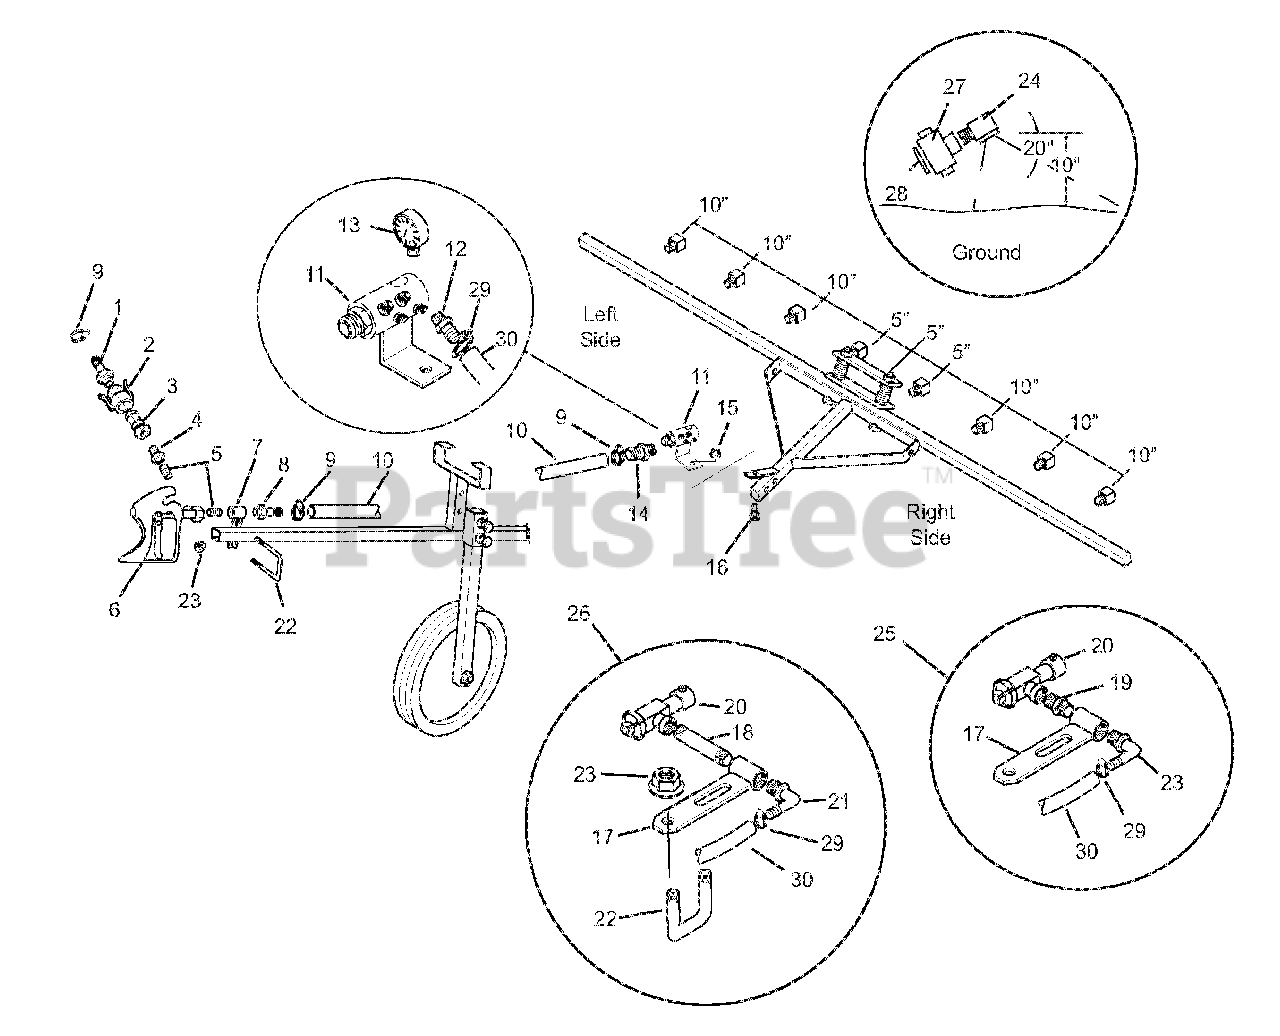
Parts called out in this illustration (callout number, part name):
1	Adapter, 3/4" MNPT to 1/2" HB
2	Adapter, 3/4" FNPT to 3/4" Q.C. Female
3	Adapter, 3/4" FNPT to 3/4" Q.C. Male
4	Adapter, 3/4" MNPT to 1/2" FNPT
5	Nipple, 1/2" MNPT x 1/1/8"
6	Spray Gun Assembly
7	Coupler Weldment
8	Adapter, 1/2" MNPT to 3/4" HB
9	Clamp, Hose
10	Hose, 3/4" x 42"
11	Manifold Assembly
12	Adapter, 1/4" MNPT to 3/8" HB
13	Pressure Gauge, Oil Filled
14	Adapter, 3/4" MNPT to 3/8" HB
15	Nut, 3/8-16 Nyloc
16	Bolt, 3/8-16 x 1 Hex
17	Bracket, Nozzle Mount
18	Nipple, 1/4 x 3", MNPT
19	Nipple, 1/4 Close MNPT
20	Diaphragm Check Valve
21	Fitting, 90° 1/4" MNPT x 3/8" HB
22	U-Bolt, 5/16-18 x 1-3/8 x 2 UNC
23	Nut, 5/16-18 Lock Serrated Flange
24	Nozzle, MC 2.5 SS
25	Nozzle Bracket Assembly
26	Nozzle Bracket Assembly, Center
27	Adapter Cap
28	Seat Gasket
29	Clamp, .31-38 Worm Drive #6206SS
30	Hose, 3/8 x 24"
